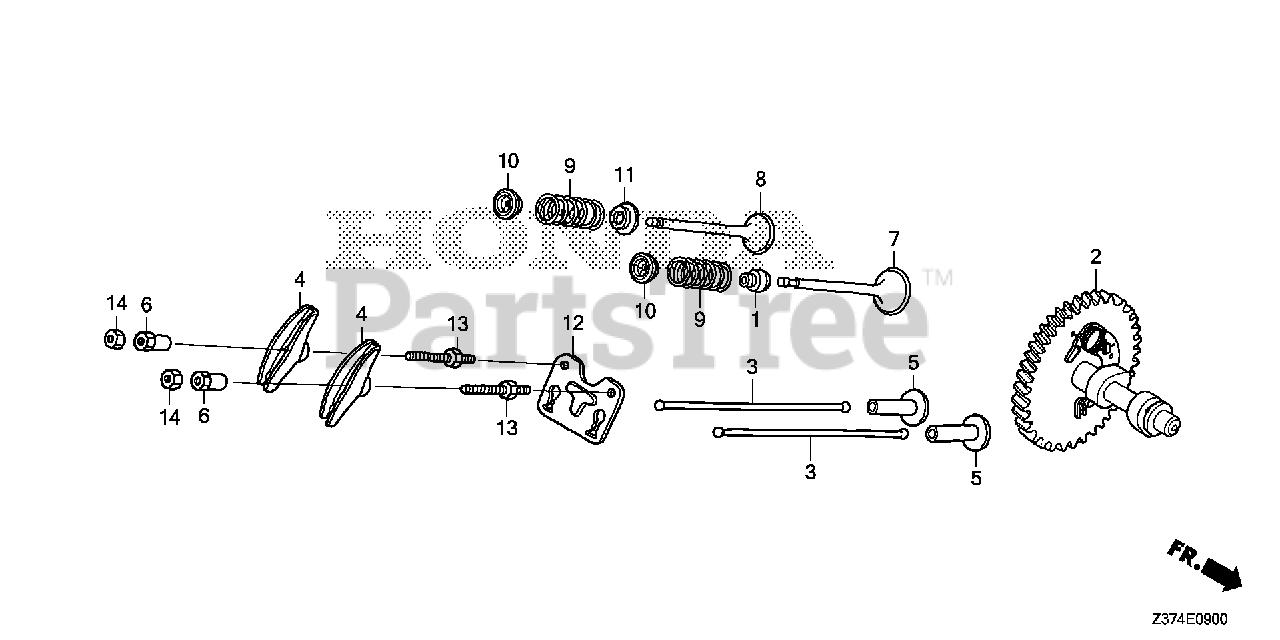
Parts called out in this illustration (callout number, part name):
1	SEAL, VALVE STEM
2	CAMSHAFT (STD)
4	ARM, VALVE ROCKER
5	LIFTER, VALVE
6	PIVOT, ROCKER ARM
7	VALVE, IN.
8	VALVE, EX. (FI)
9	SPRING, VALVE
10	RETAINER, IN. VALVE SPRING (EXHAUST SIDE)
11	SEAT, VALVE SPRING
12	GUIDE, PUSH ROD
13	BOLT, PIVOT (8MM)
14	NUT, PIVOT ADJ.
